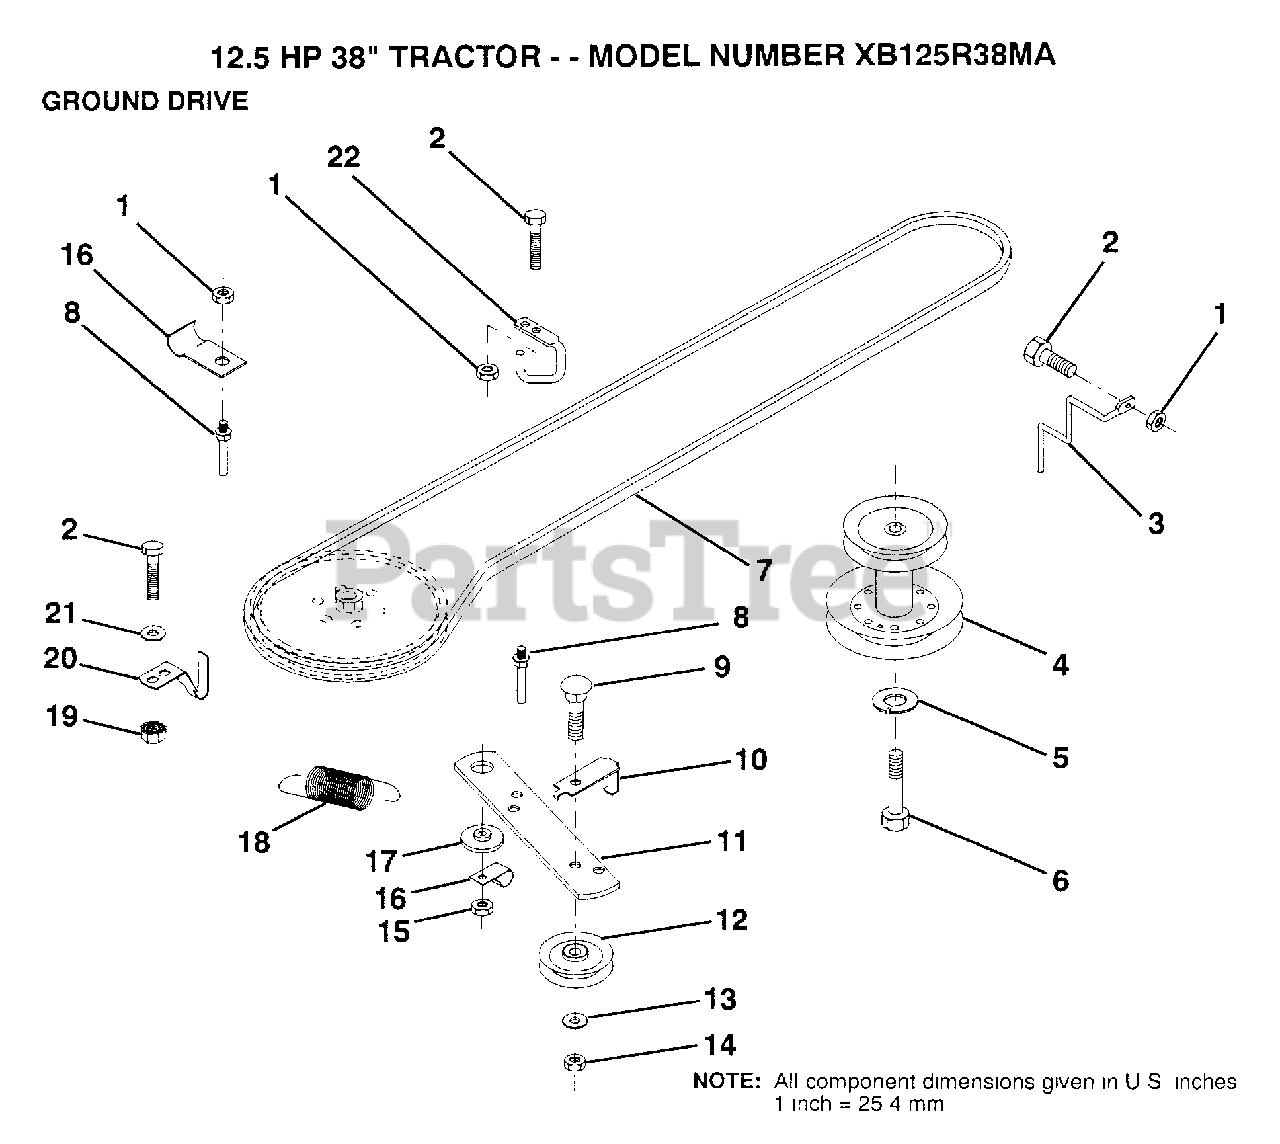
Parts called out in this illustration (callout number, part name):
2	BOLT
3	KEEPER MWR DR BLT
5	LOCKWASHER
6	BOLT
7	BELT
8	"KEEPER,DRIVE BELT"
9	BOLT
10	"KEEP,IDLER DR BEL"
13	WASHER
14	LOCKNUT
16	"CLIP,INSULATOR"
17	SPACER RETAINER
20	"KEEPER,DR BELT "
21	WASHER
22	"KEEPER,FRA DR BEL"
